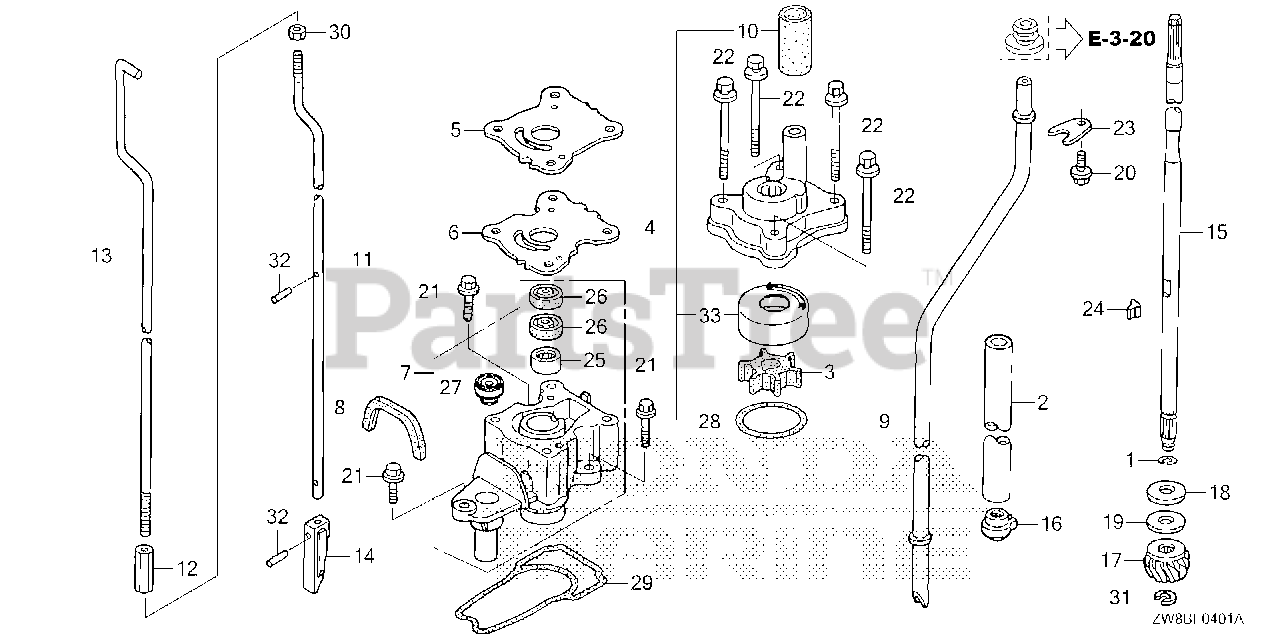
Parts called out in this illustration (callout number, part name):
1	CLIP, VALVE GUIDE
2	GUIDE, OIL (UL)
3	IMPELLER, PUMP (UL)
4	HOUSING ASSY., IMPELLER
5	COVER, IMPELLER
6	GASKET, IMPELLER
7	HOUSING, WATER PUMP (UL)
8	GROMMET, WATER PUMP HOUSING
9	TUBE, WATER (UL)
10	RING, WATER TUBE SEAL
11	ROD B, SHIFT (UL)
12	JOINT, SHIFT ROD
13	ROD A, SHIFT (L)
14	ROD, PUSH
15	SHAFT, VERTICAL (UL)
16	SLINGER, OIL (UL)
17	GEAR, PINION
18	WASHER A, THRUST BEARING
19	WASHER B, THRUST BEARING
19	WASHER C, THRUST BEARING
20	BOLT, FLANGE (6X12) Use from Frame SN 1005249.
21	BOLT, FLANGE (6X20) (ENGINE NO.)
22	BOLT-WASHER (6X90)
23	PLATE, WATER TUBE SETTING
24	KEY, WOODRUFF
25	BEARING, NEEDLE (15X21X12)
26	SEAL, WATER (15X24X5)
27	SEAL, WATER (6MM)
28	O-RING (42.2X2.4)
29	O-RING, WATER PUMP HOUSING
30	NUT, HEX. (6MM)
31	E-RING (8MM)
32	ROLLER (2.5X11.8)
33	LINER, PUMP
